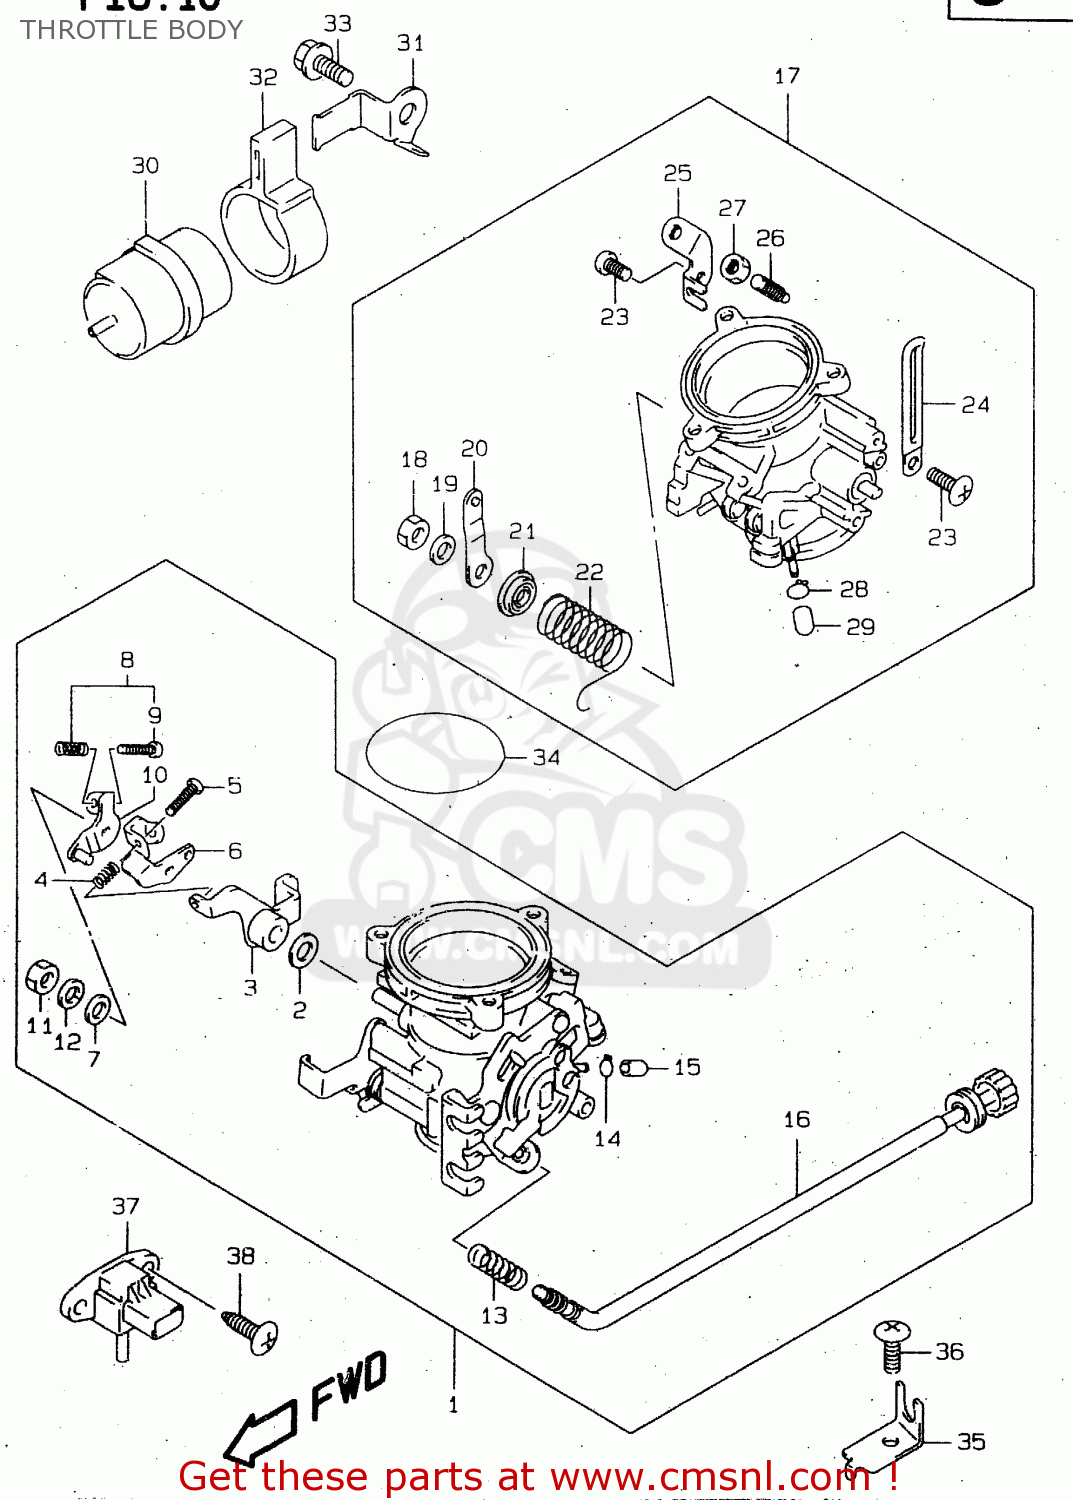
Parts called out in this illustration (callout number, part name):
1	BODY ASSY,THROTTLE FR
2	PACKING (NAS)
3	LEVER ASSY
4	SPRING
5	SCREW
6	LEVER
7	RING
8	SCREW SET,ADJUST
9	SCREW
10	LEVER ASSY
11	NUT
12	WASHER,LOCK
13	SPRING
14	CLIP
15	CAP
16	ADJUST SCREW ASSY
17	BODY ASSY,THROTTLE RR
18	NUT
19	WASHER,LOCK
20	LEVER ASSY
21	RING
22	SPRING
23	SCREW
24	CLAMP(L:65)
25	BRACKET
26	SCREW
27	NUT
28	CLIP
29	CAP
30	CHAMBER,VACUUM
31	PLATE VACUUM CHAMBER
32	BAND,VACUUM CHAMBER
33	PLUG(10X10)
34	O RING(D:2.4,ID:60.5)
35	PLATE,IDLE ADJUST
36	SCREW 6X12
37	SENSOR,MAP
38	SCREW
